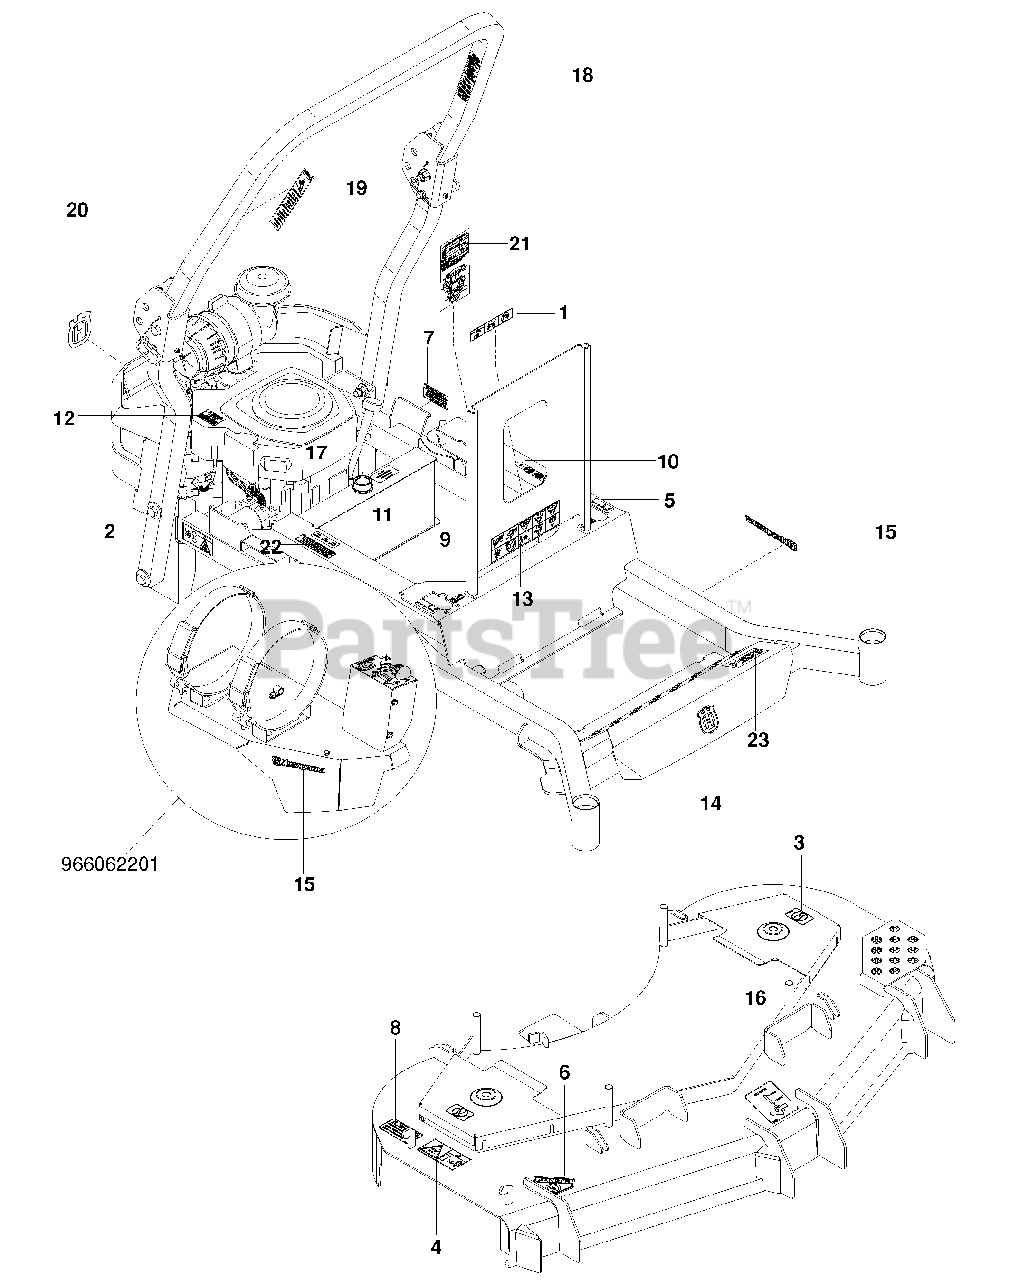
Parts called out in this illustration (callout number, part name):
1	Decal, Battery Warning
2	Bolt 7/16-20 X 1 1/2 Hex Nyl
3	Decal, No Step
4	Decal, Severing
5	Decal, Motion Control
6	Decal, Cpsc
7	Decal, Prop 65
8	Decal, Warning
9	Decal, F.S.T
10	Decal, Park Brake
11	Decal, Oil Tank
12	Decal, Exhaust
13	Decal, Warning
14	Decal, Crown H
15	Decal, Husqvarna
16	Decal, Belt Routing
17	Decal, Fuse
18	Decal, Rops
19	Decal, Rops Warning
20	Decal, Crown H
21	Decal, Service
22	Decal, Spark Arrestor
23	Decal, Pz5426
